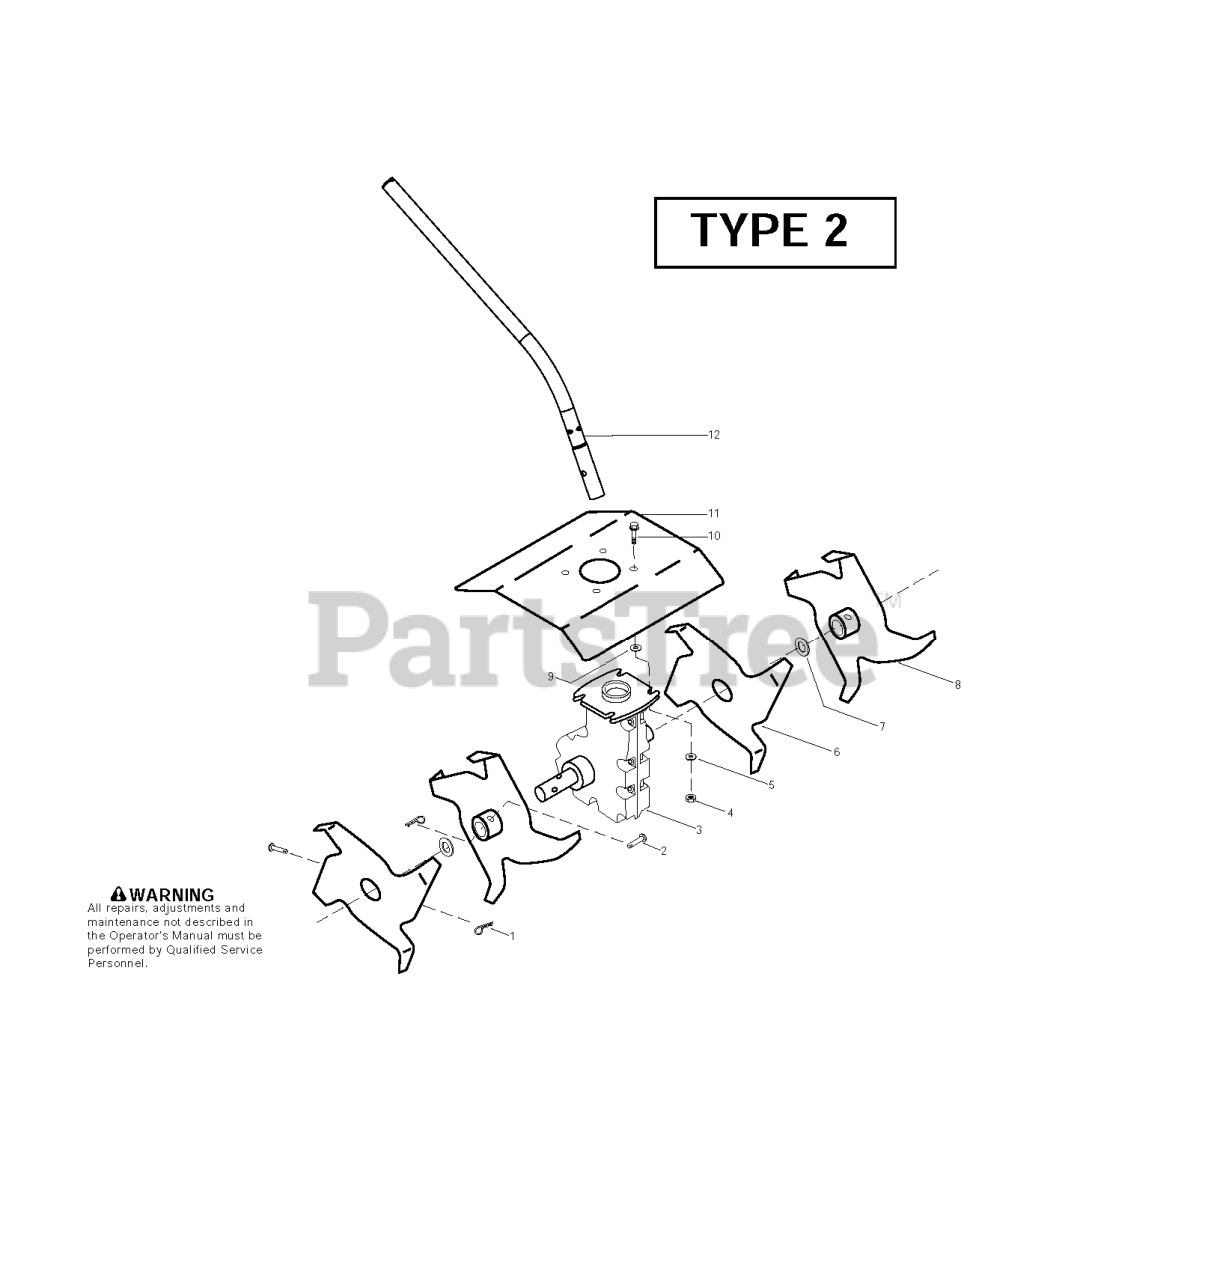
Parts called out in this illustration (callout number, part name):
1	RETAINER,HAIRPIN
2	PIN,CLEVIS
3	GEAR ASSY GEARBOX
5	WASHER,FLAT
6	TINE,RIGHT OUTSIDE/LEFT INSIDE
7	WASHER,FELT
8	TINE,LEFT OUTSIDE/RIGHT INSIDE
9	WASHER,FLAT
10	BOLT,WASHER HEAD
